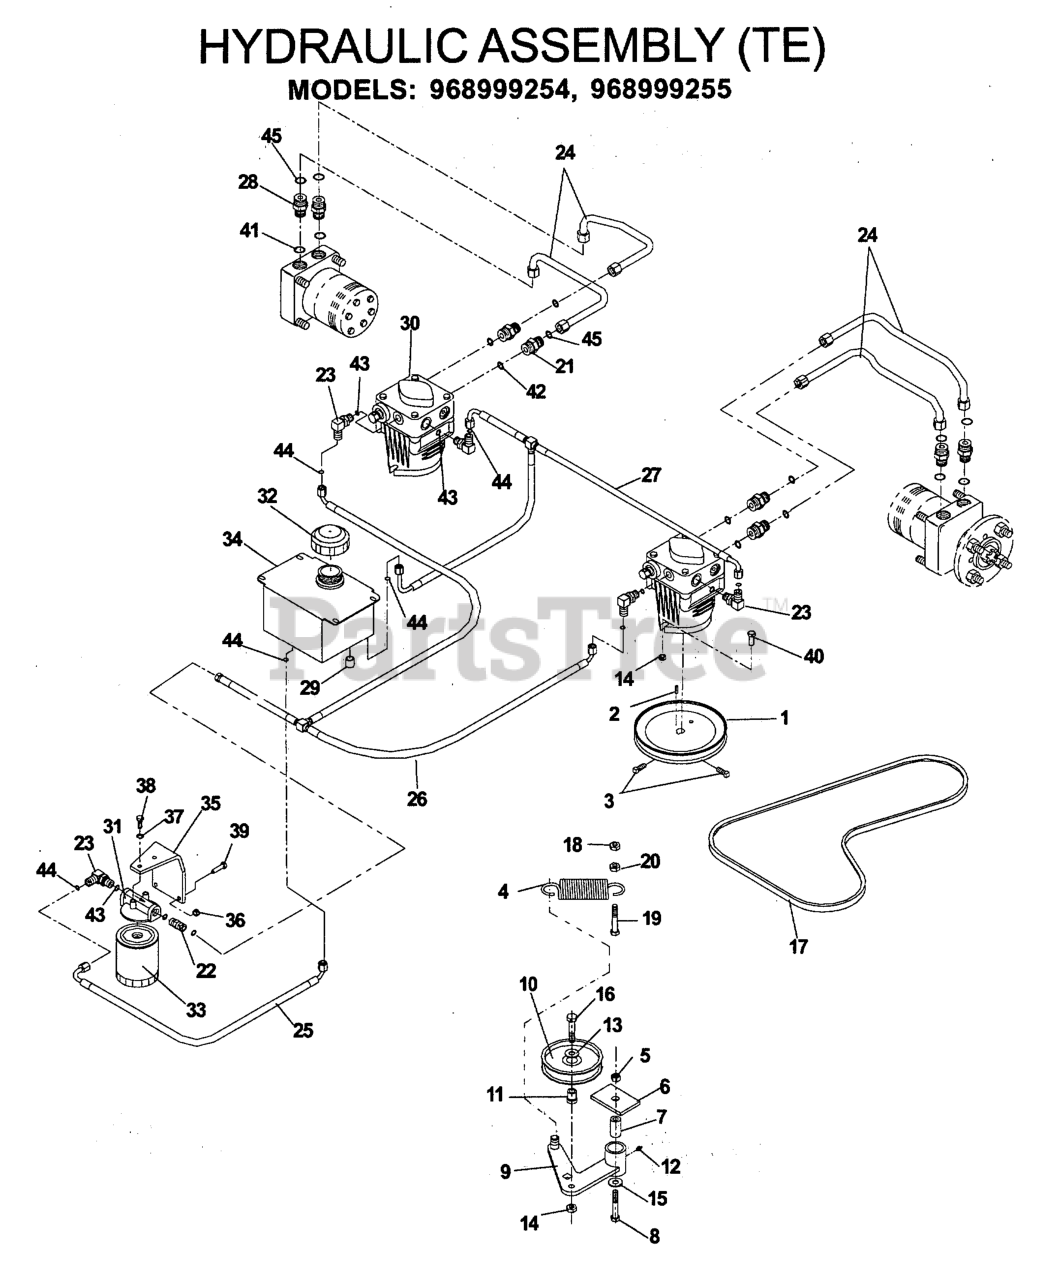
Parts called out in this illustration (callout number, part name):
2	KEY 5 MM SQ X 25 MM
3	SCREW 5/16C X 5/8 SQ HEAD
5	NUT 1/2-13 HEX NYLOC ZD
7	PIVOT BUSHING
8	HCS 1/2C X 3 1/4
9	IDLER ARM WLDT
10	IDLER PULLEY
11	BUSHING, IDLER FLANGE
12	ZERK
13	WASHER 3/8 FLAT
14	NUT 3/8C CENTERBLOCK
15	WASHER 1/2 FLAT
16	HCS 3/8-16 X 1 3/4 GR5
17	PUMP BELT
18	NUT 3/8-16 NYLOC
19	HCS 3/8C X 2
20	NUT 3/8C WHIZ
21	FITTING, STRAIGHT F6400-8-8-0
22	HYDRAULIC FITTING
23	ELBOW, F6801-6-6-0 90 DEGREE
24	HYDRAULIC HOSE
26	T-ASSEMBLY
29	NUT 9/16-18 JIC CAP
30	10CC PUMP W/RTN'S
31	FILTER HEAD
32	HYDRAULIC CAP
33	HYDRAULIC OIL FILTER
35	OIL FILTER BRKT
36	NUT.1/4-20.HEX.NYLOC.ZD
37	LOCKWASHER 1/4"
38	HCS 1/4C X 5/8
39	HCS 1/4C X 3/4 HCS
40	4CS 3/8C X 1 SERRATED HEAD
